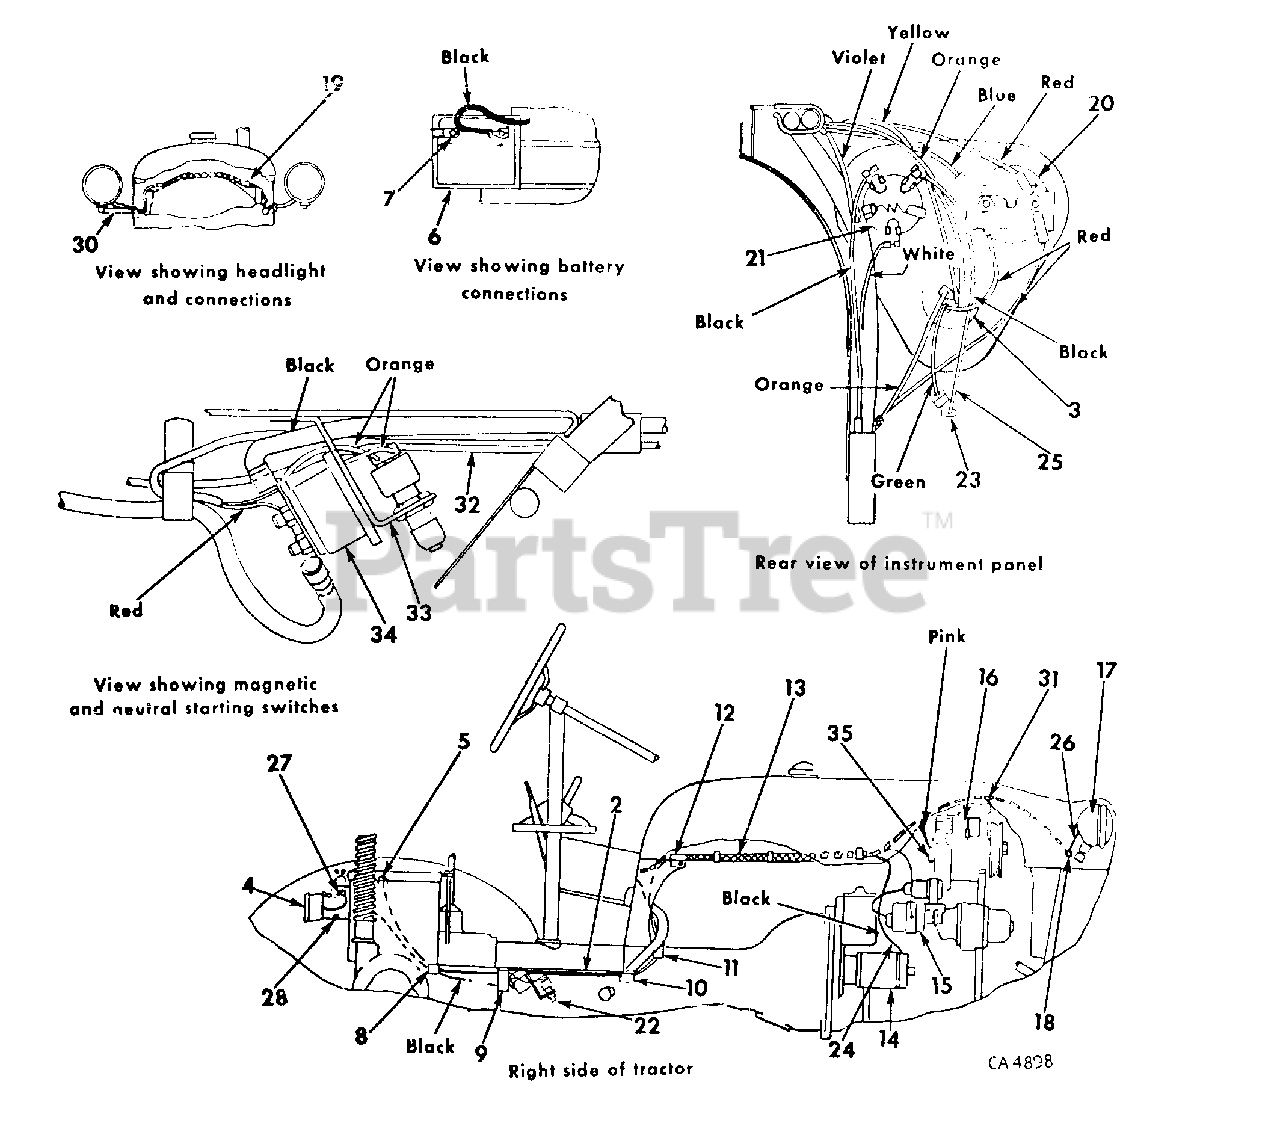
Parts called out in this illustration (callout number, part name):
2	CABLE ASSY, REAR LIGHT
3	SWITCH ASSY, BATTERY IGNITION KEY
4	LIGHT ASSY, TAIL
5	GROMMET, BATTERY BOX
6	BATTERY 12 VOLT-
7	STRAP W/BOLT, IH-356092-R91, BATTERY 10
8	CLIP CABLE
9	CLIP THIRD BOLT FROM REAR
10	STRAP CABLE WRAPPING
11	CLIP, INSIDE RIGHT SIDE FUEL TANK SUPPORT
12	CLIP, CABLE HARNESS -RH SIDE-
13	HARNESS ASSY, CABLE
14	MOTOR ASSY, CRANKING
15	BATTERY, IGNITION UNIT
16	ALTERNATOR ASSY
17	LIGHT ASSY, HEAD
18	GROMMET, RUBBER NO 6 -IN HOOD-
19	CLIP HEAD LIGHT CABLE HARNESS
20	INDICATOR ASSY, CHARGE
21	SWITCH ASSY, LIGHTING
22	SWITCH ASSY NEUTRAL STARTING
23	HOUSING ASSY, FUSE
24	CABLE ASSY, MAGNETIC SWITCH TO CRANKING MOTOR
25	CABLE ASSY, FUSE HOUSING TO LIGHTING SWITCH
26	BODY, CONNECTOR
27	CLIP REAR LIGHT CABLE
28	CLIP, TAIL LIGHT CABLE
30	POST HEAD LIGHT
31	CLIP, CABLE HARNESS
32	HARNESS ASSY, NEUTRAL STARTING SWITCH
33	BRACKET, NEUTRAL STARTING SWITCH
34	SWITCH ASSY MAGNETIC
35	RESISTOR -25 OHM-
IH-120512HX	GROUND BOLT ASSY, TERMINAL
